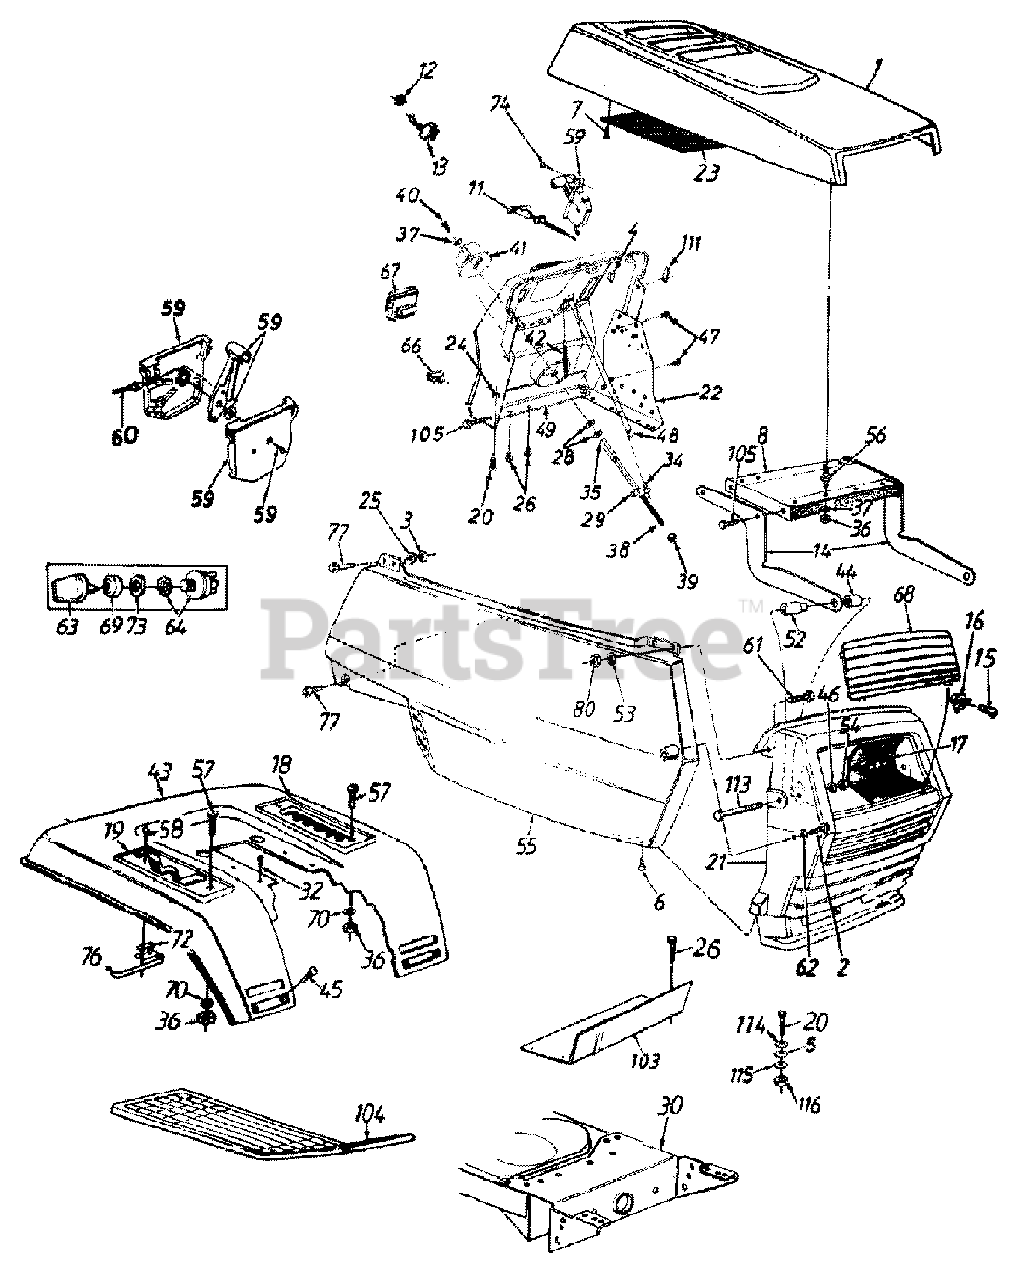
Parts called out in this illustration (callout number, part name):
1	Hood
2	Hex Wash. B-Tap Scr. 1/4 x .62" Lg.
3	Bolt Retainer 1/4" I.D.
4	Retainer Clip
6	Truss Mach. B-Tap Scr. #10 x .5" Lg.
7	Hex Wash. Hd. AB-Tap Scr. #8 .5" Lg.
12	Hex Nut 1/2-27 Thd.
13	Toggle Switch
16	Twist Lock-Lamp Socket
17	Reflector-Headlight
18	Forward/Reverse Index Brkt.
19	7-Speed Selector Plate
20	Hex Bolt 5/16-18 x .75" Lg.
21	Grille
24	Hex Sems Nut 5/16-18 Thd.
26	Hex Wash. Hd. B-Tap Scr. 5/16-18 x .5" Lg.
28	Fl-Wash. 3/8" I.D. x .875" O.D.
29	Adj. Ferrule 3/8-8 Thd.
32	Hex Wash. Hd. AB-Tap Scr. 5/16 x .75" Lg.
34	Hairpin Clip
35	"E"-Ring .375" Dia.
36	Hex Nut 1/4-20 Thd.
37	Bell-Wash. .265" I.D. x .75"
38	Adjustment Rod
39	Hex Nut 3/8-8 Twin Thd.
40	Hex Bolt 1/4-20 x .75" Lg.
41	Plastic Knob
42	Ext. Spring 3.21" Lg.
45	Carriage Bolt 1/4-20 x .50" Lg.
46	Fl-Wash. .328" I.D. x .68" O.D.
47	Hex Wash. Hd. Scr. 1/4-20 x .5" Lg.
48	Indicator Strip
52	Shld. Spacer .33" I.D.
53	Fl-Wash. .281" I.D. x .5" O.D.
54	Hex Cent. L-Nut 5/16-18 Thd.
55	Side Cover-R.H.
56	Double Ended Stud 1/4-20 Thd.
57	Truss Mach. Scr. 1/4-20 x .75" Lg.
58	Hex Wash Hd. AB-Tap Scr. #8 x .5" Lg.
59	Throttle Control Box Ass'y.
60	Throttle Control Wire 22" Lg.
61	Hex Bolt 1/4-20 x .62" Lg.
62	Fl-Wash. .281" I.D. x .73" O.D.
64	Ignition Switch
66	Light Switch
67	Ammeter
68	Lens
69	Ignition Switch Cap
70	L-Wash. 1/4" I.D.
72	Insulator Nut Plate
73	Ignition Switch Nut
74	Truss Mach. AB-Tap Scr. #10 x .5" Lg.
76	Reverse Safety Switch
77	Hex Wash. Hd. Tap Scr. 1/4 x .75" Lg.
80	Hex L-Nut 1/4-20 Thd.
105	Hex Tap Scr. 1/4-20 x .5" Lg.
111	Speed Nut 1/4-20 Thd.
113	Hex Bolt 5/16-18 x 2.75"
114	Fl-Wash. .349" I.D. x 1" O.D.
115	L-Wash. 5/16" I.D.
116	Hex Nut 5/16-18 Thd.
